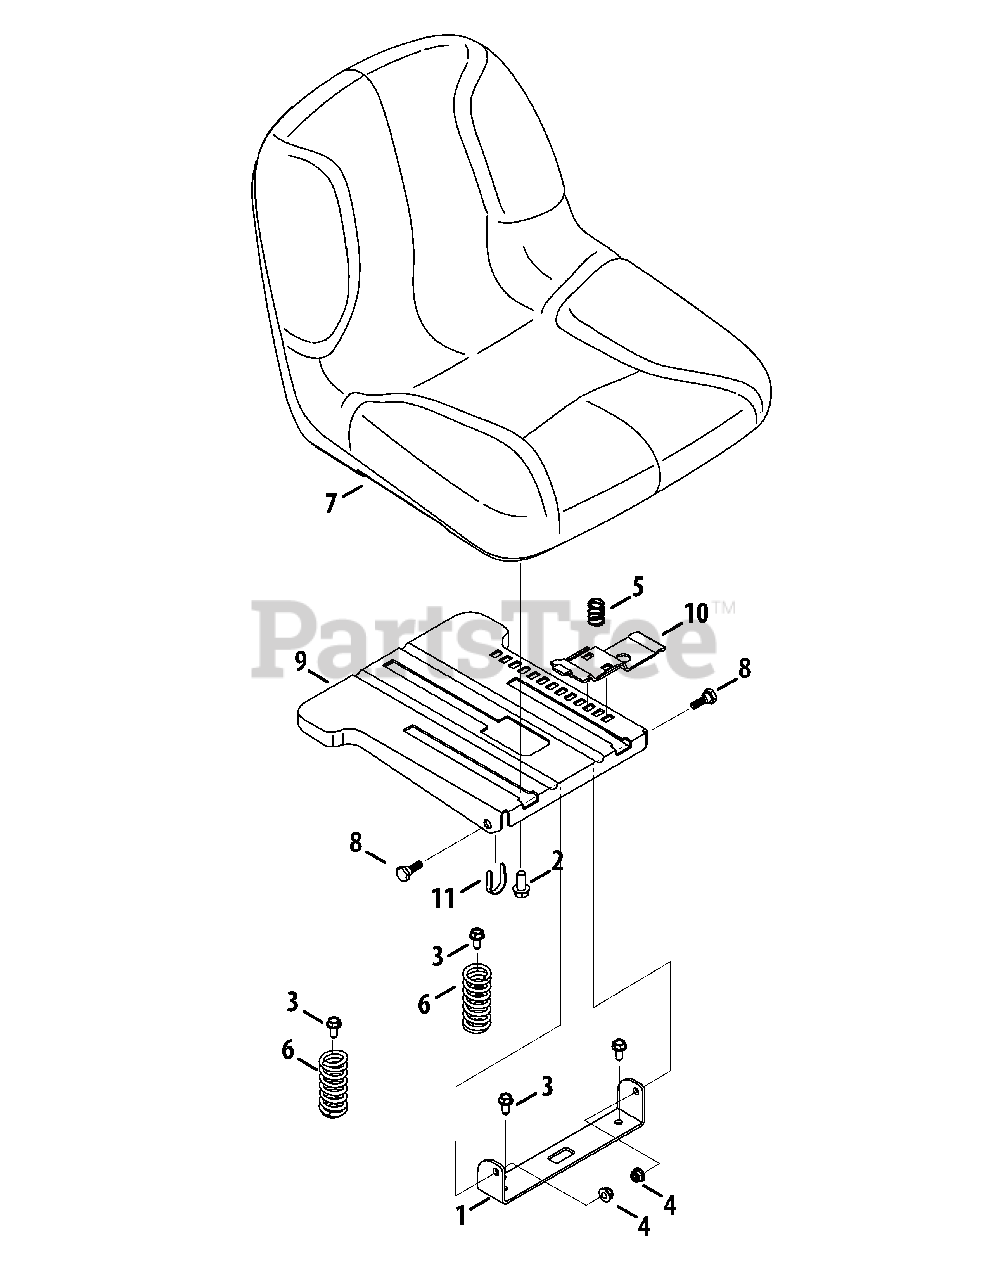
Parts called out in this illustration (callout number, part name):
1	Seat Bracket
2	Hex Flange Bolt, 3/8-16 x .875
3	Hex Washer Screw, 5/16-18 x .750
4	Flange Lock Nut, 5/16-18
5	Compression Spring, .68 x 1.065 x .055
6	Compression Spring, 1.50 x 3.90 x .200
7	Seat
8	Shoulder Screw, 5/16-18 x .437 x .268
9	Seat Mount Bracket
10	Seat Adjustment Lever
